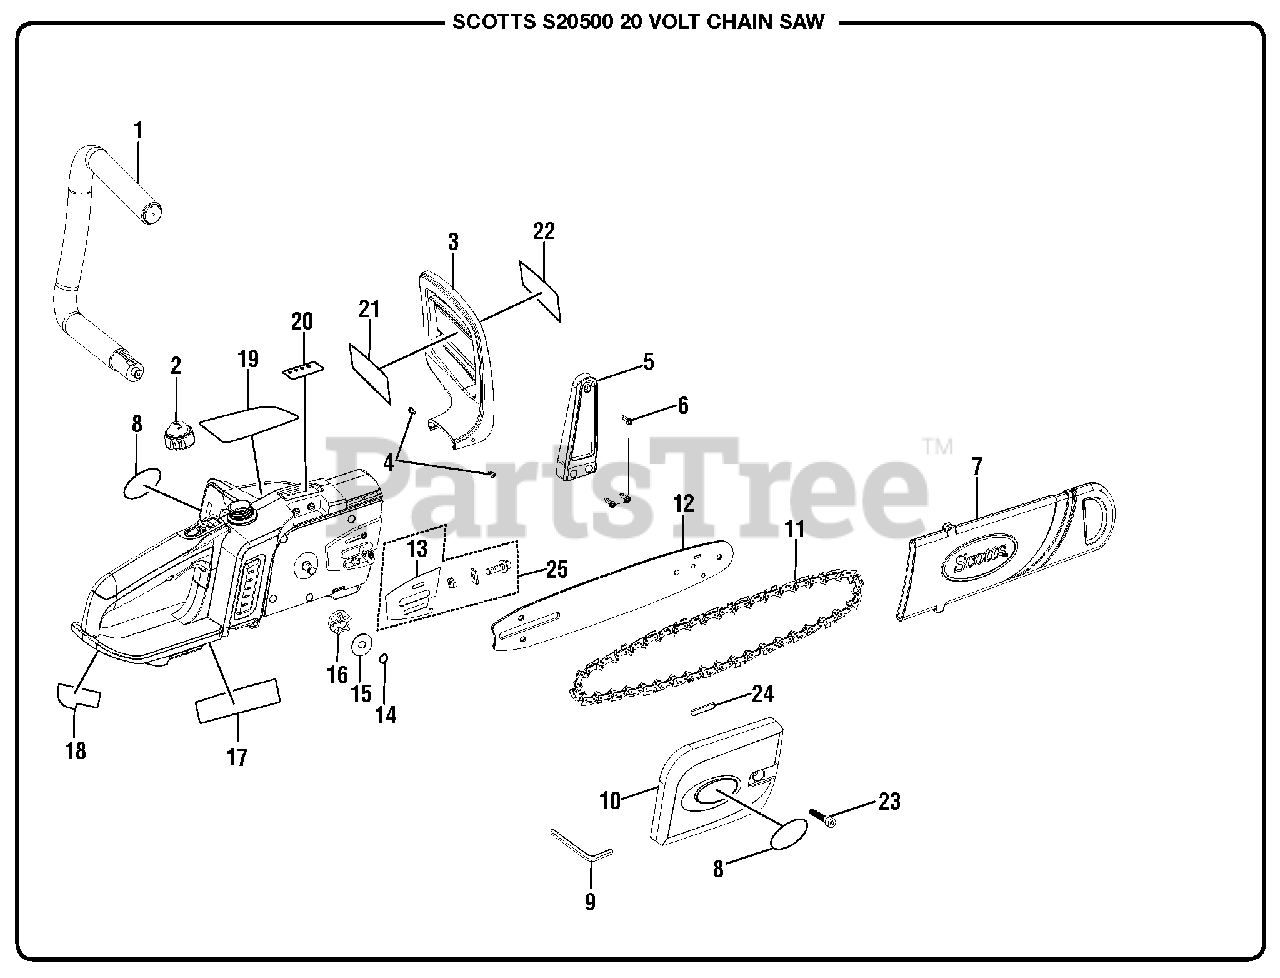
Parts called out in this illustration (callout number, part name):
1	Left Front Handle
2	Oil Cap Assembly
3	Guard w/Labels
4	Screw (M3 x 8 mm)
5	Right Front Handle
6	Screw (M4 x 14 mm)
8	Logo Label
9	Hex Key (5mm x 4mm)
10	Bar Cover w/Level
12	Bar Assembly
13	Rubber Gasket
14	Retaining Ring
15	Cover Plate
17	Warning (Fr/Sp)
18	Data Label
19	Warning Label
20	Fuel Indicator
21	Warning Icon Label
22	Lithium Ion Label
24	Rubber Plate
25	Chain Adjustment Assmebly
